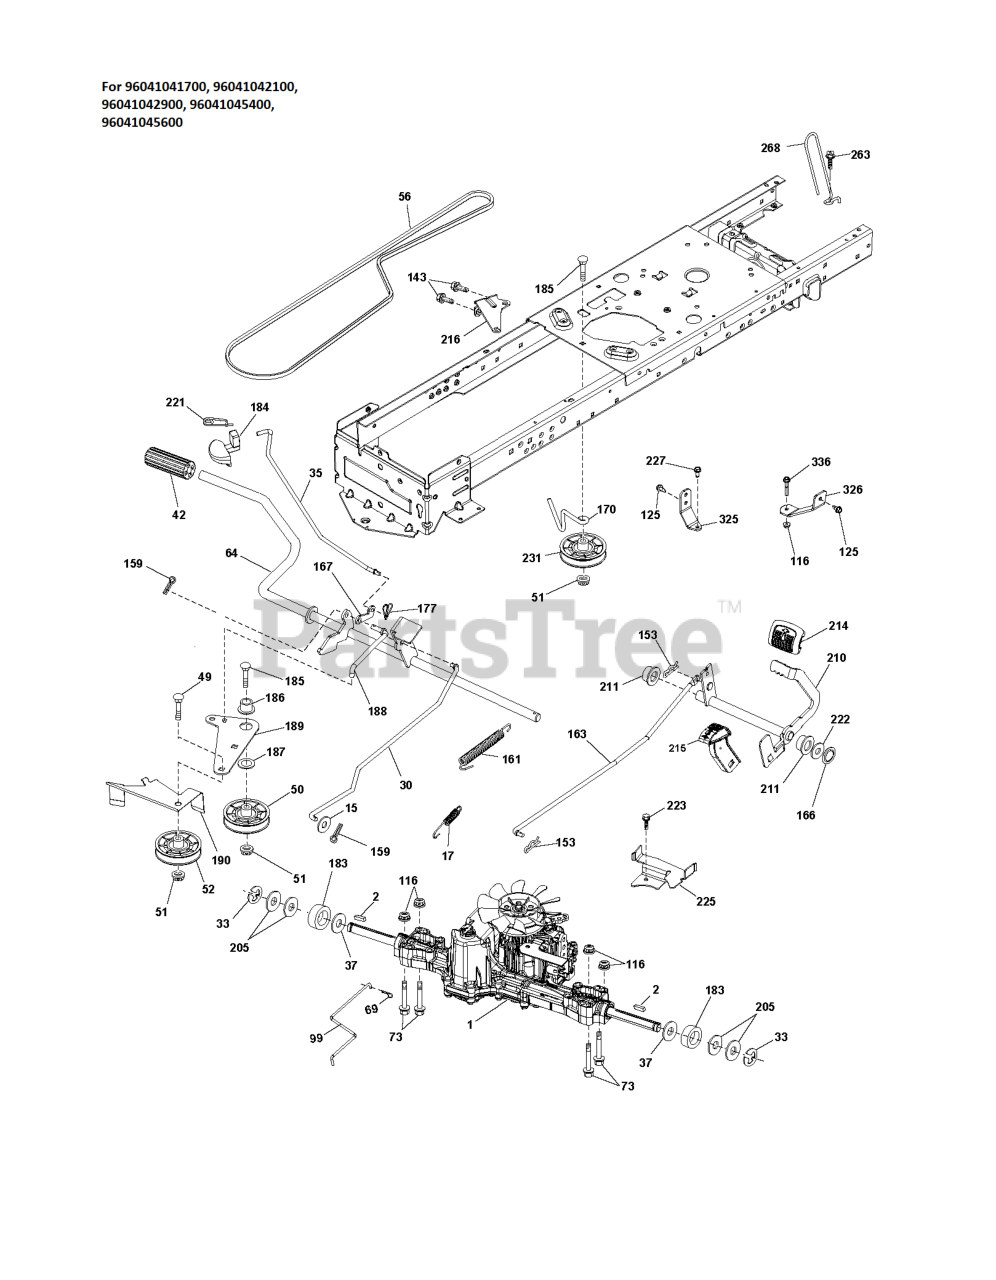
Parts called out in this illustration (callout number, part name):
1	TRANSAXLE(K46BT).PDL.
2	SQUARE KEY
15	WASHER PLAIN WASHER 3/8 X 0.08
17	SPRING.BRAKE.K46.GREEN
30	ROD.BRAKE.K46
37	WASHER.HARDENED
42	PAD, FOOT PEDAL
50	IDLER.FLAT.910.OFFSET
51	NUT.HEX.FLANGE.3/8-16.LOCKNUT
52	IDLER.V-GROOVE.910.OFFSET
64	SHAFT.ASM.PEDAL.BRK.CNTR
69	HAIRPIN.SOFT.ZINC.059X1.125
99	ARM.PIVOTING.TCRD.GEN2.5.BAGGE
125	BOLT.HEX.HD.WASHER.5/16-18X.75
153	RETAINER M
161	SPRING, RETURN LT
166	NUT.PUSH.625
167	SERVICE KIT LATCH LATCH.BRAKE.
170	KEEPER.CENTER SPAN.1.688
177	GSPW Retainers
177	PIN COTTER;LOCKING;BOWTIE;1IN
183	SPACER AXLE
184	HANDLE.PARKNG BRK.PRED.LT.428
186	SPACER.RETAINER
188	LINK.CLUTCH.GROUND DRIVE.LONG
189	SERVICE KIT BELLCRANK
190	KEEPER.BELLCRANK.DRIVE
210	ROCKER.ASM.PEDAL.CONTR
211	BEARING.NYLON
214	PEDAL.FORWARD.PAD.TEX
215	PEDAL.COVER.REVERSE.CRD.X428BK
216	BRACKET.PULLEY.IDLER.W/TEX
221	RETAINER.SPRING.CLIP.H
222	WASHER 21/32 X 1-1/4 X 10 GA.
225	SERVICE KIT KEEPER BELT KEEPER
231	IDLER.V-GROOVE.1.688.OFFSET
263	SCREW, 3/8-16X3/4
268	Mufflers
325	BRACKET TORQUE STRAP
326	BRACKET TORQUE STRAP
